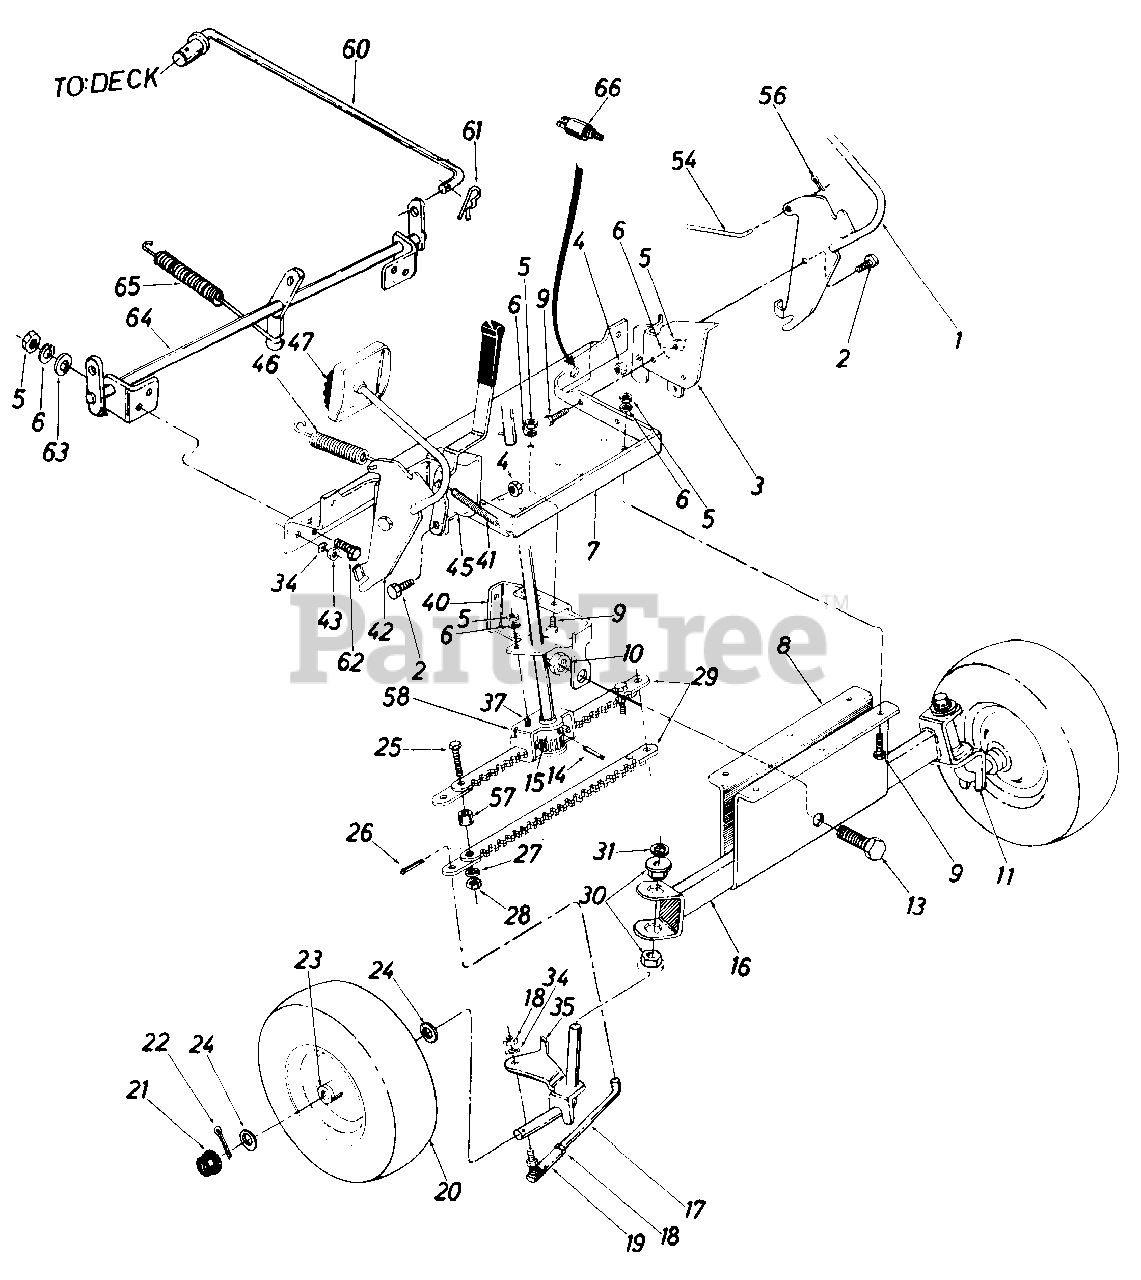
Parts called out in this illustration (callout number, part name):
1	Foot Pedal Ass'y.
2	Shld. Scr. .500" Dia. x .170
3	L.H. Brake Pivot Brkt.
4	Hex Center L-Nut 3/8-16 Thd.
5	Hex Nut 5/16-18 Thd.
6	Spring L-Wash. 5/16" Scr.
7	Front Frame
8	Front Pivot Brkt. Ass'y.
9	Hex Sems Scr. 5/16-18 x .75
10	Hex Center L-Nut 5/8-18 Thd.
11	Front Axle Ass'y. L.H.
13	Hex Scr. 5/8-18 x 1.31 Lg.
14	Spring Pin 3/16 Dia. x 1.50" Lg.
15	Spur Gear 12 Tooth
16	Pivot Bar Ass'y.
18	Hex Jam Nut 3/8-24 Thd.
19	Ball Joint
20	Front Wheel Ass'y. - Comp.
21	Hub Cap
22	Cotter Pin 1/8" x 1-1/4" Lg.
23	Flange Bearing
24	Flat Wash. .625 I.D.
25	Hex Scr. 1/4-28 x 1.25" Lg.
26	Cotter Pin 3/32 Dia. x .75 Lg.
27	Spring L-Wash. 1/4 Scr.
28	Hex Cent. L-Nut 1/4-28 Thd.
29	Steering Rack
30	Flange Bearing
31	Push Nut .625 Shaft
34	Spring L-Wash. 3/8 Scr.
35	Front Axle Ass'y. R.H.
37	Cross Recess Truss Hd. Scr. 5/16-18 x .75" Lg.
40	Steering Box Support
41	Spring
42	Foot Pedal Ass'y.
43	Hex Nut 3/8-16 Thd.
45	R.H. Pivot Brkt.
46	Brake Tension Spring
47	Pad - Vinyl-Brake
54	Clutch Rod
56	Cotterpin 3/32 Dia. x .75 Lg.
58	Steering Housing
60	Stabilizer Rod
61	Inter. Cotter Pin 3/8" Dia.
62	Hex Bolt 5/16-18 x .75" Lg.
63	Fl-Wash. .344" I.D. x .62" O.D.
64	Stabilizer Shaft Ass'y.
66	Safety Switch (Clutch)
